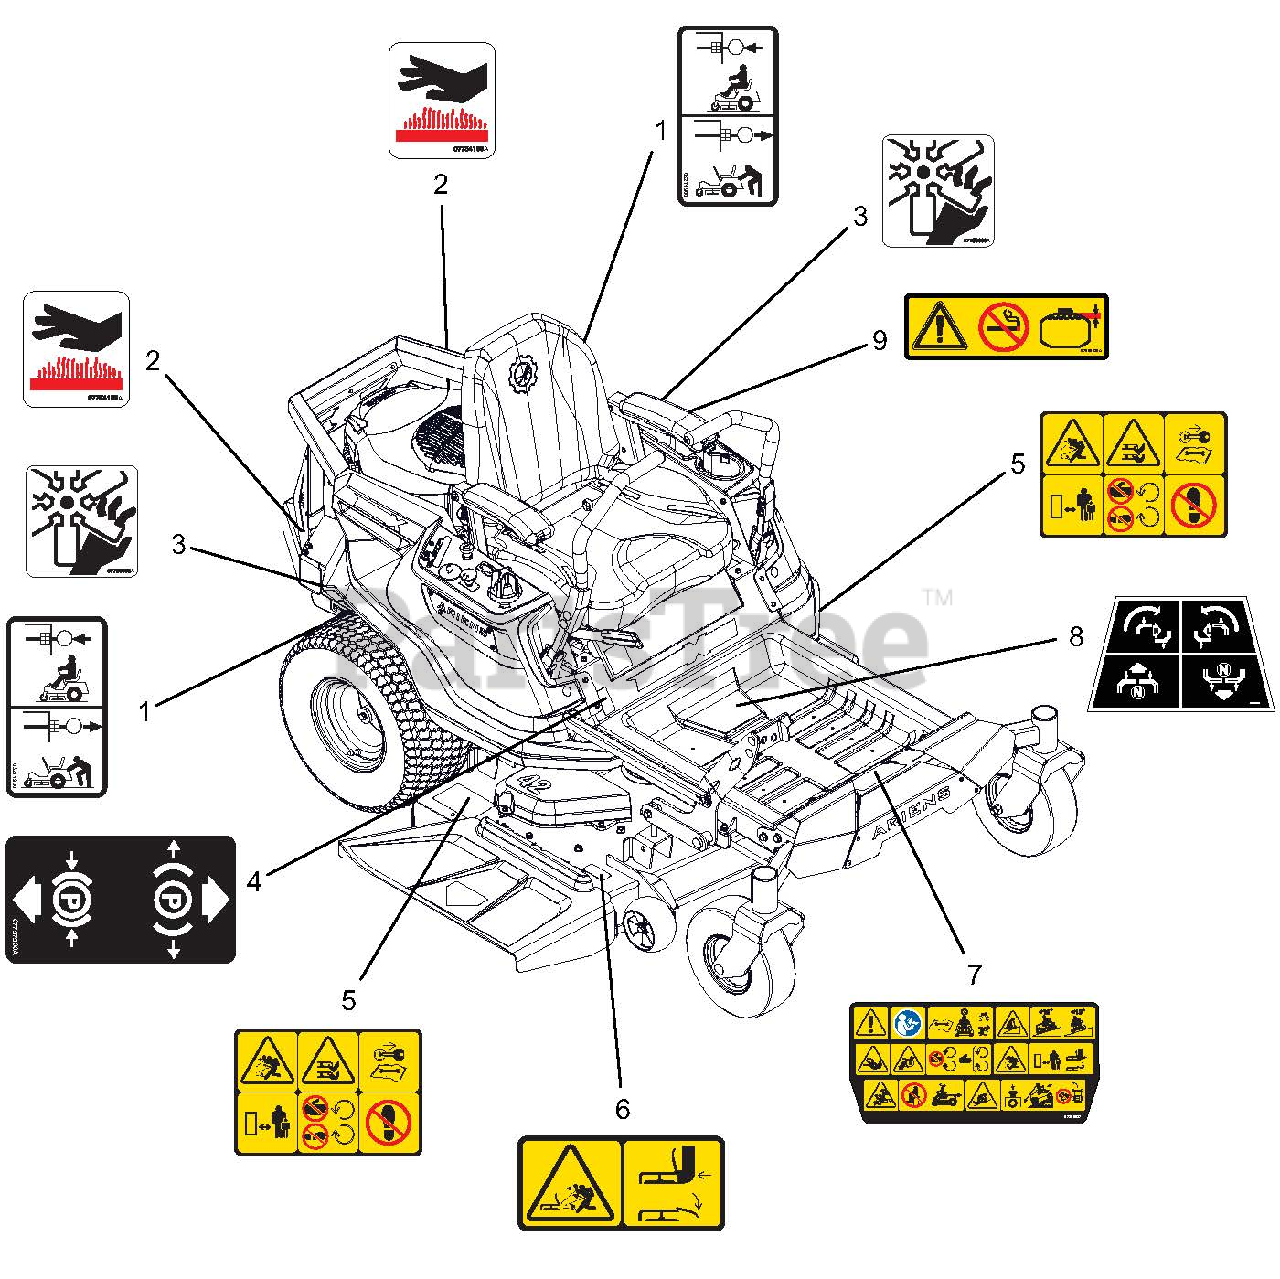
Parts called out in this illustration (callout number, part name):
1	DECAL, TRANSMISSION DISCONNECT
2	DECAL, HOT SURFACE
3	DECAL, DANGER FAN
4	DECAL, PARKING BRAKE LEVER
5	DECAL, SAFETY - MOWER DECK
6	DECAL, SAFETY - DECK GUARDING
7	DECAL, MAIN SAFETY
8	DECAL, STEERING
9	DECAL, FUEL WARNING
